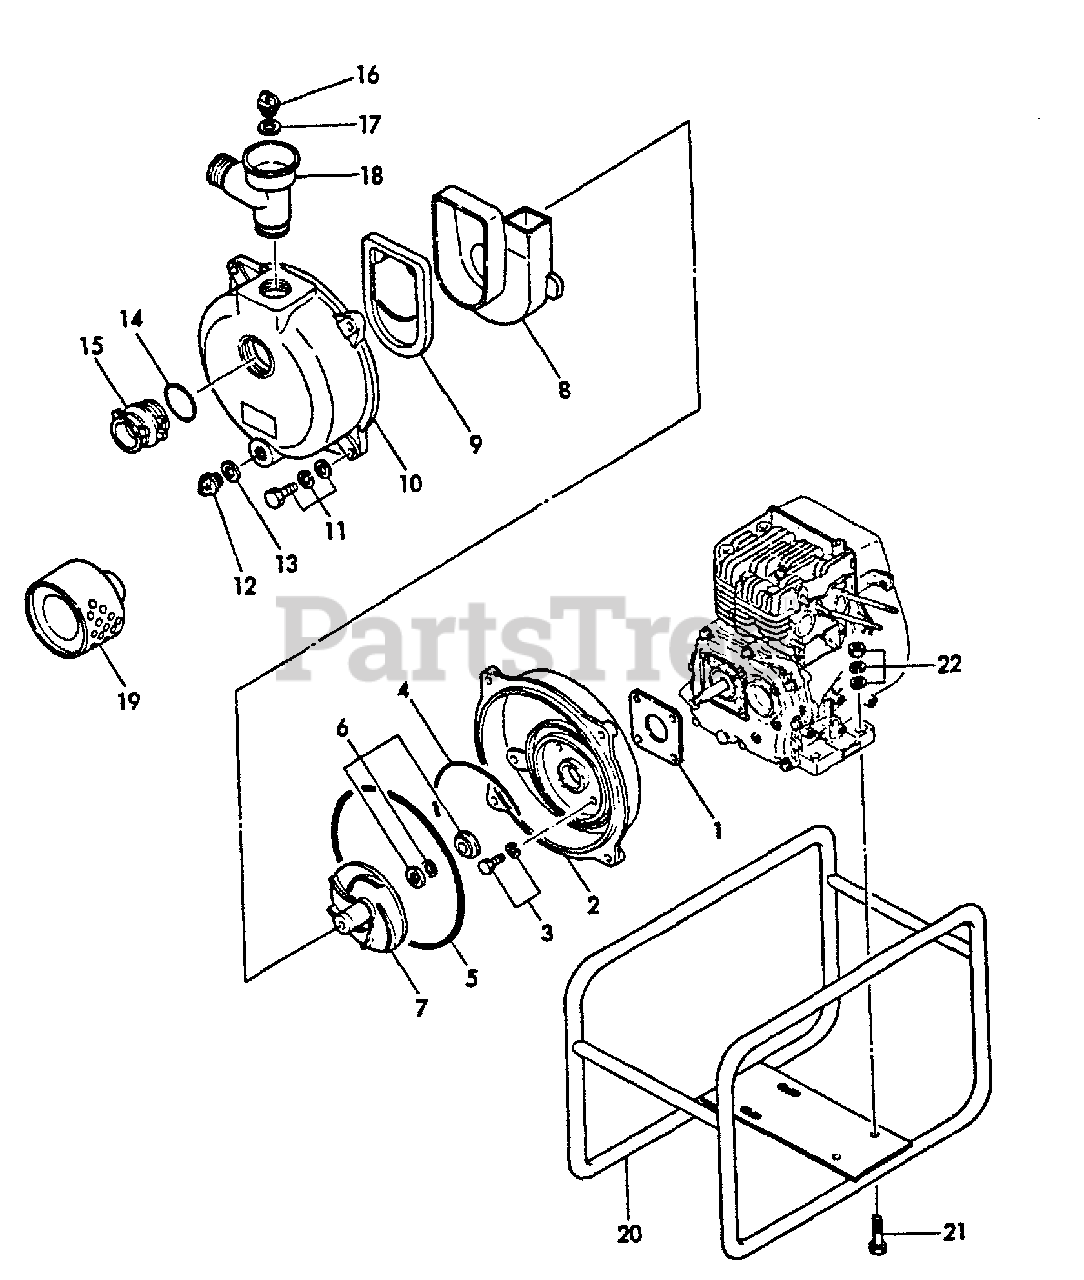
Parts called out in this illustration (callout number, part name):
1	GASKET, CASING
2	CASING
3	BOLT, CASING
4	GASKET, THREAD
5	O-RING, CASING
6	SEAL, MECHANICAL
7	IMPELLER, SHIM 0.2 Y80020000000
8	HOUSING
9	VALVE, STOP
10	COVER
11	BOLT, COVER
12	CAP, DRAIN
13	GASKET, CAP
14	O-RING, HOSE NIPPLE
15	NIPPLE, HOSE
16	CAP, DELIVERY
17	GASKET, DELIVERY
18	BEND, DELIVERY
19	STRAINER, DEBRIS
20	BASE
21	BOLT, ENGINE
22	NUT, ENGINE
